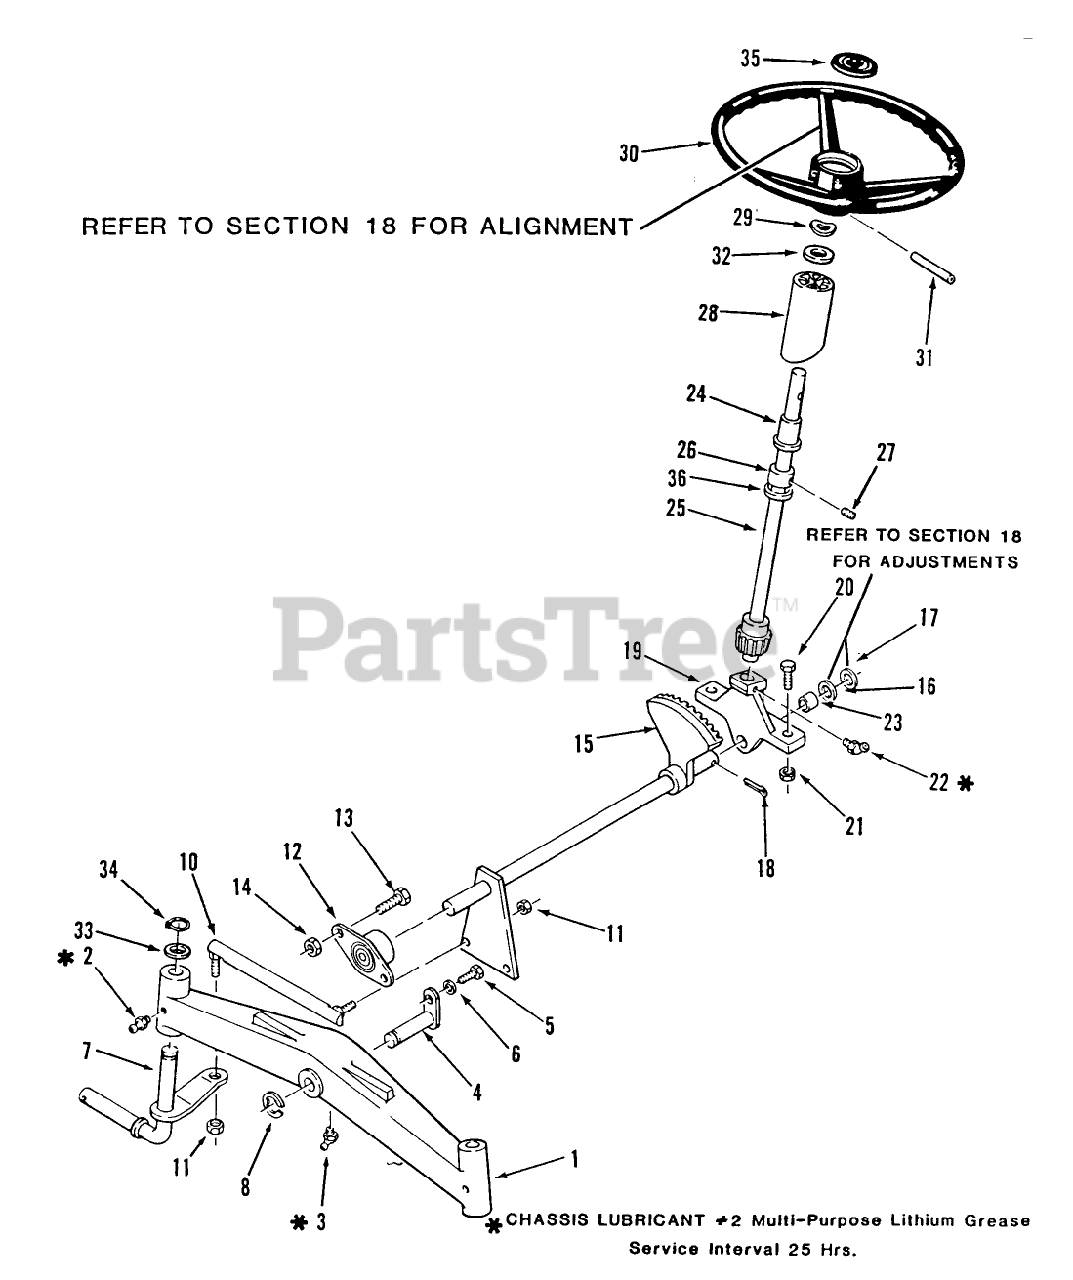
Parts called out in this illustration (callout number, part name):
3	Grease Fitting 45?
4	PIN AND PLATE ASM
8	E-RING
12	BEARING-FLANGED
16	WASHER-SHIM
17	WASHER
22	FITTING-GREASE
23	BEARING-BRONZE
24	BEARING-FLANGED
28	TUBE-STEERING
29	WASHER-BOWED
32	WASHER-FLAT
33	WASHER
36	RING-RETAINING
